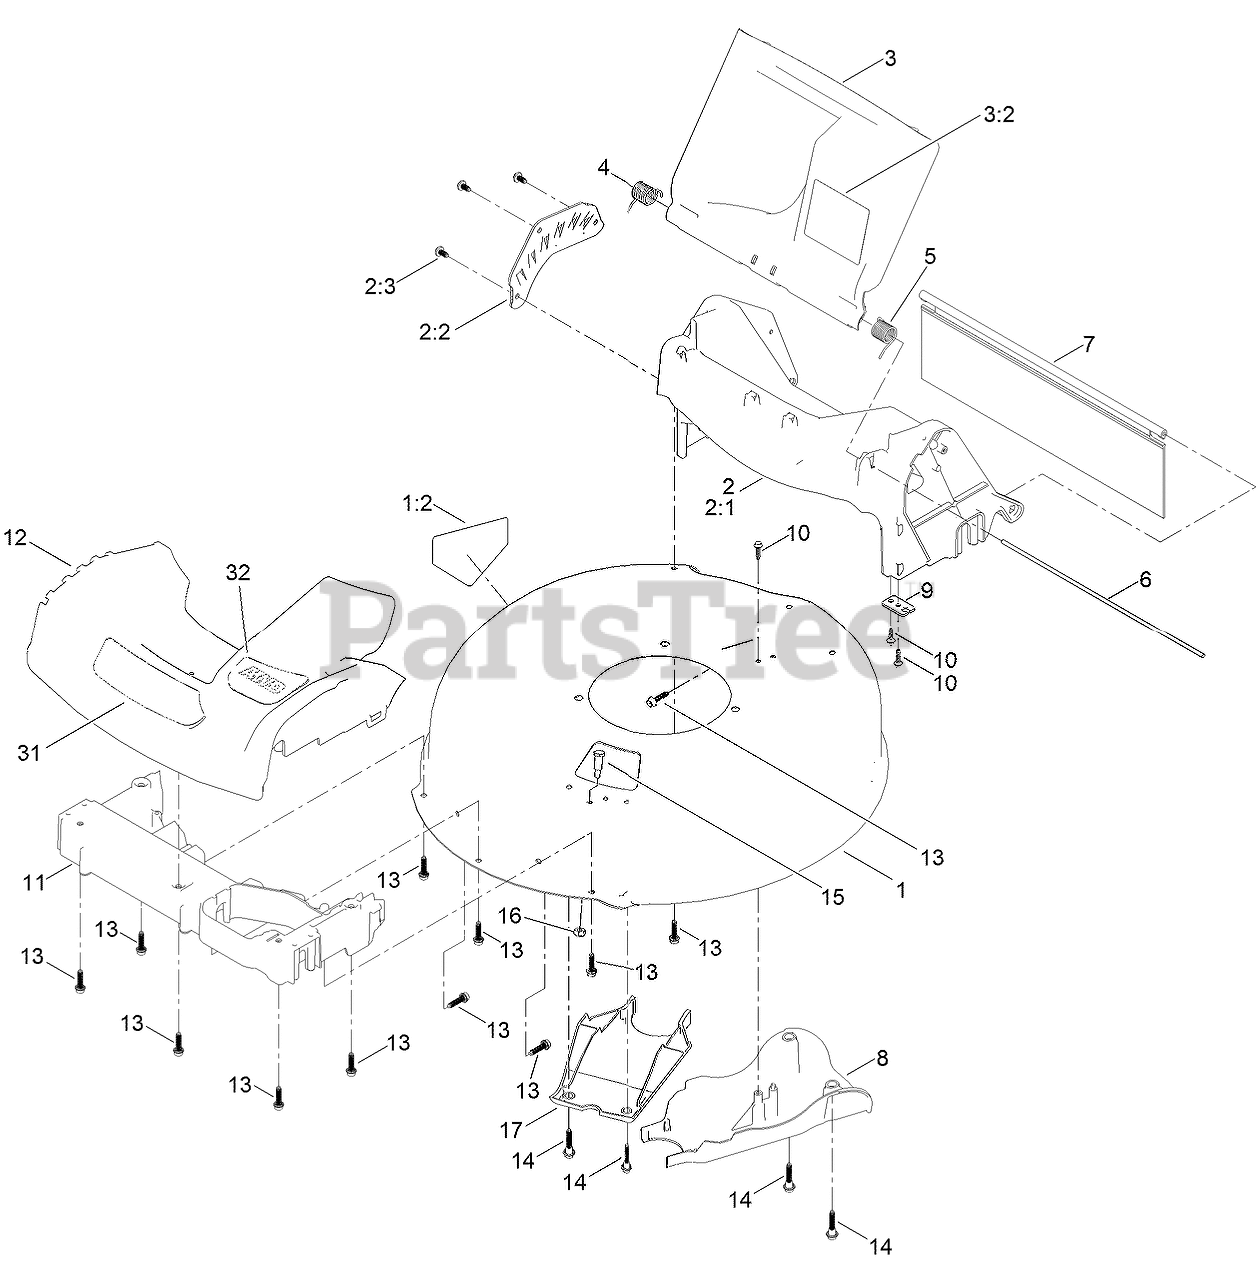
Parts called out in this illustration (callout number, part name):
1	HOUSING ASM
1:2	DECAL-DANGER
2	CHUTE ASM
2:1	CHUTE
2:2	PLATE-HOC
2:3	SCREW-PLASTIC TPH
3	REAR DEFLECTOR ASM
3:2	DECAL-WARNING
4	SPRING-TORSION
5	SPRING-TORSION
6	ROD-DOOR
7	SHIELD-TRAILING
8	COVER-BELT
9	BRACKET-CABLE
10	SCREW-HWH
11	MOUNT-BUMPER
12	BUMPER
13	SCREW-FLANGE, PLASTIC
14	SCREW-SHOULDER, HHF
15	BOLT-SHOULDER
16	NUT-LOCK, NI
17	COVER-BELT, FRONT
31	DECAL-DECK
32	DECAL-COVER
